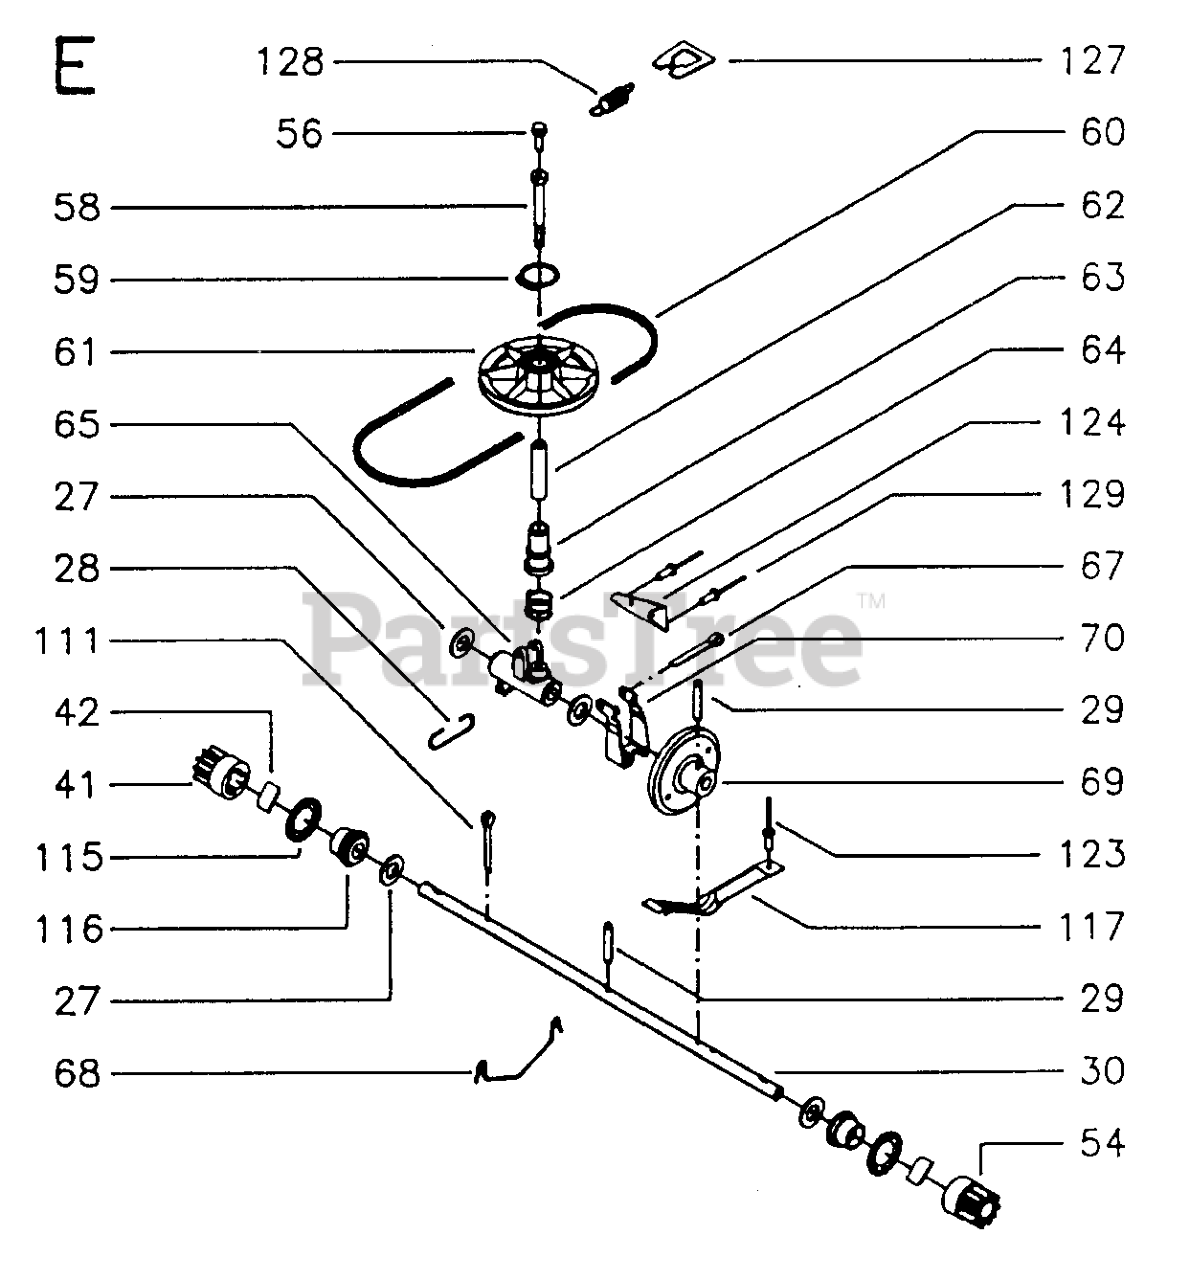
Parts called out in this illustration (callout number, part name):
27	WASHER
28	CLIPS
41	PINION, RIGHT
42	CARRIER
54	PINION, LEFT
56	SCREW TAPTITE
60	BELT -V RUBBER/TEXTILE
61	PULLEY W/BRG
63	SLEEVE
65	HOLDER
68	HOLDER SPACER
69	WHEEL ASSY FRICTION
70	RAM
115	LOCK WASHER
123	REPL BY 516 92 38-00
127	SPRING FASTENING
